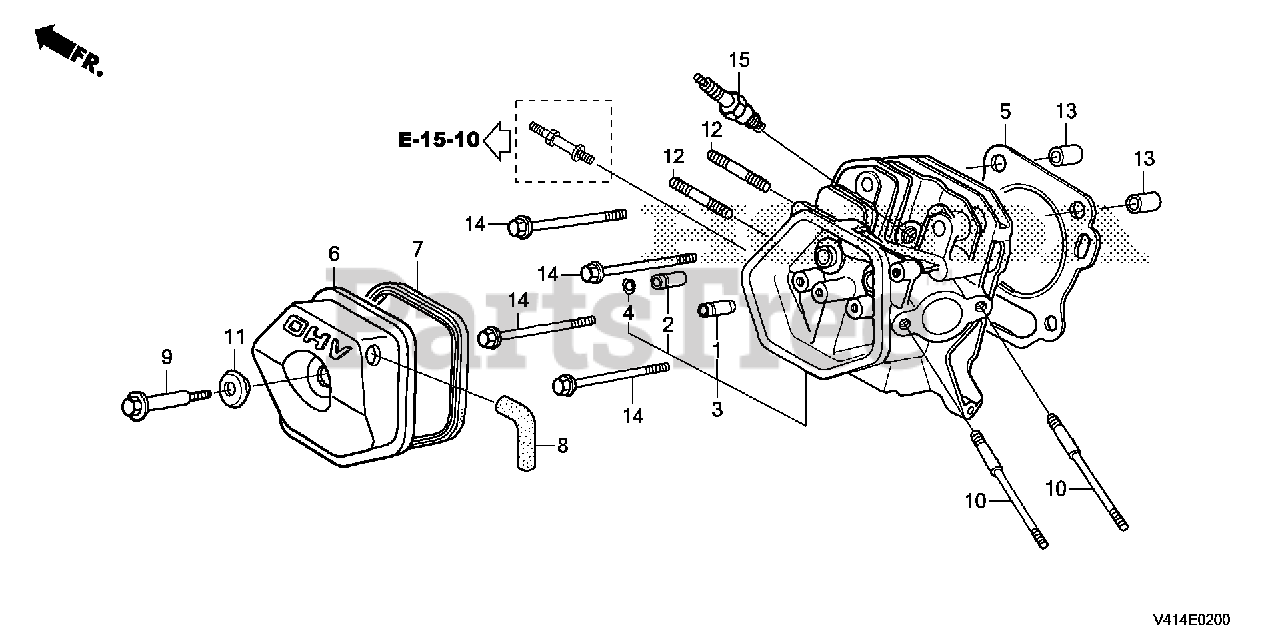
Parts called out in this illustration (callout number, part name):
1	GUIDE, VALVE (OVER SIZE)
2	GUIDE, EX. VALVE (OVER SIZE)
3	CYLINDER HEAD
4	CLIP, VALVE GUIDE
5	GASKET, CYLINDER HEAD
6	COVER, HEAD
7	GASKET, HEAD COVER
8	TUBE, BREATHER
9	BOLT, HEAD COVER
10	BOLT, STUD (8X123)
11	WASHER, HEAD COVER
12	BOLT, STUD (8X32)
13	PIN, DOWEL (12X20)
14	BOLT, FLANGE (10X80)
15	SPARK PLUG (BPR5ES) (NGK)
